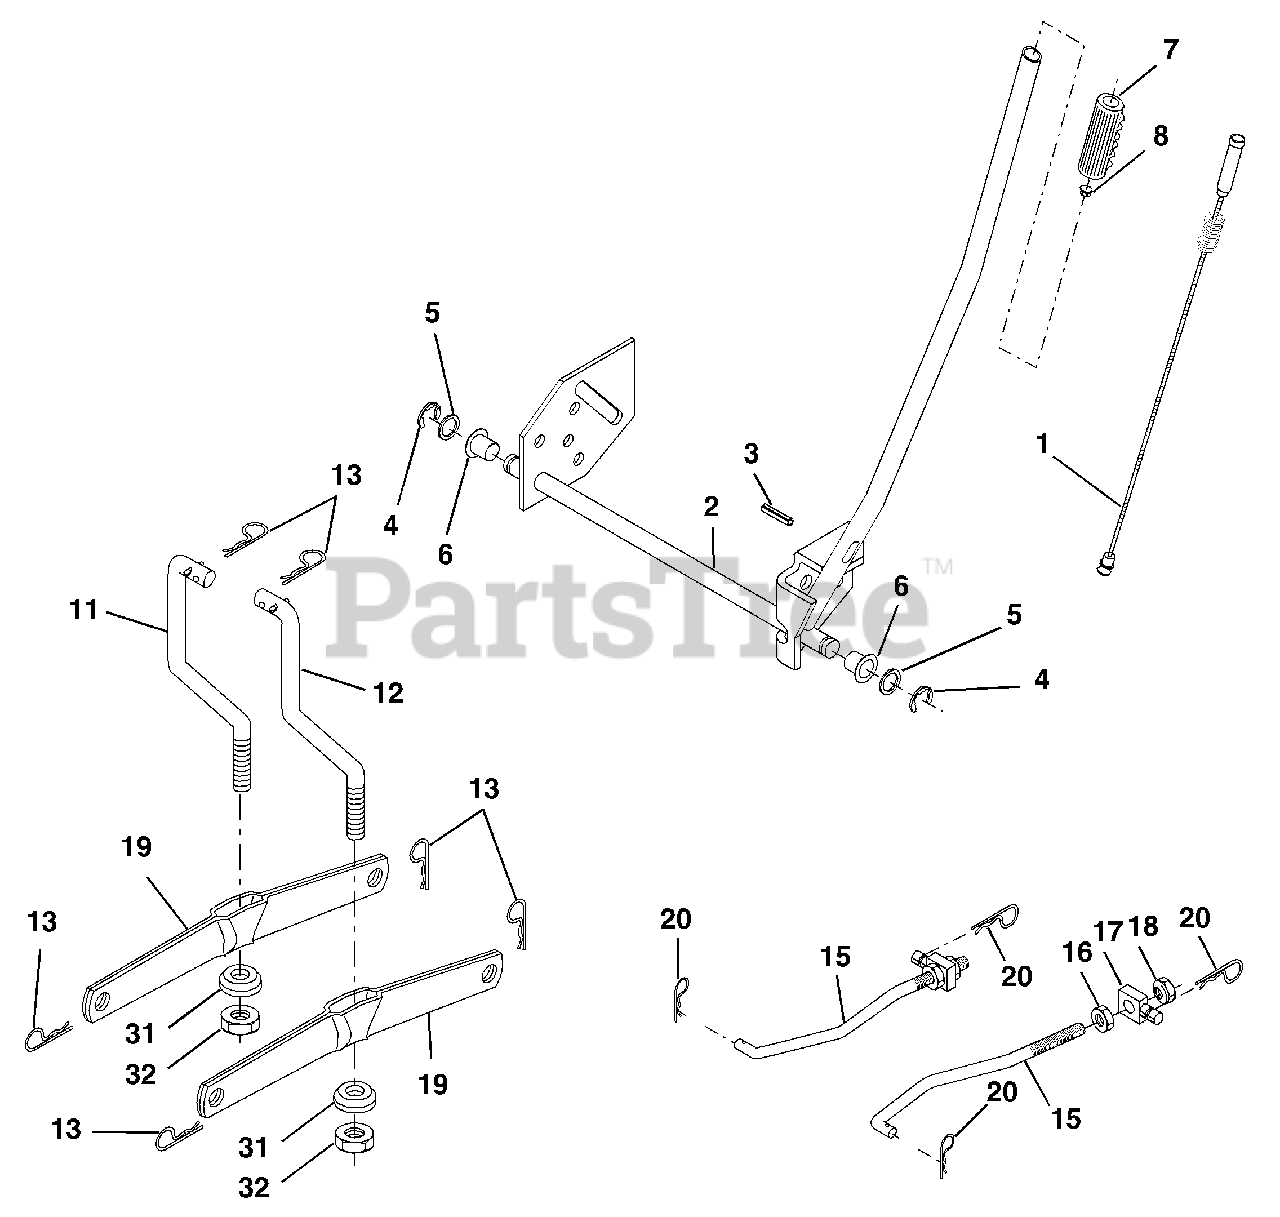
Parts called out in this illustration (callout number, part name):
1	Wire Asm Inner W/plunger LT
2	Shaft Asm Lift
3	Pin Groove
4	E Ring #5133-62
5	Washer PLTD 21/32 X 1 X 21ga
6	Bearing Nylon Blk 629 Id
7	Grip Handle Bicycle
8	Button Plunger Black
11	Link Lift LH
12	Link Lift RH
13	Retainer Spring
15	Link Front
16	Nut Jam Hex 1/2-13 Unc
18	Nut Lock W/Wsh 1/2-13 Unc
19	Arm Suspension Rear
20	Spring, Retainer
31	Bearing Pvt. Lift
32	Nut Crownlock 3/8-24
